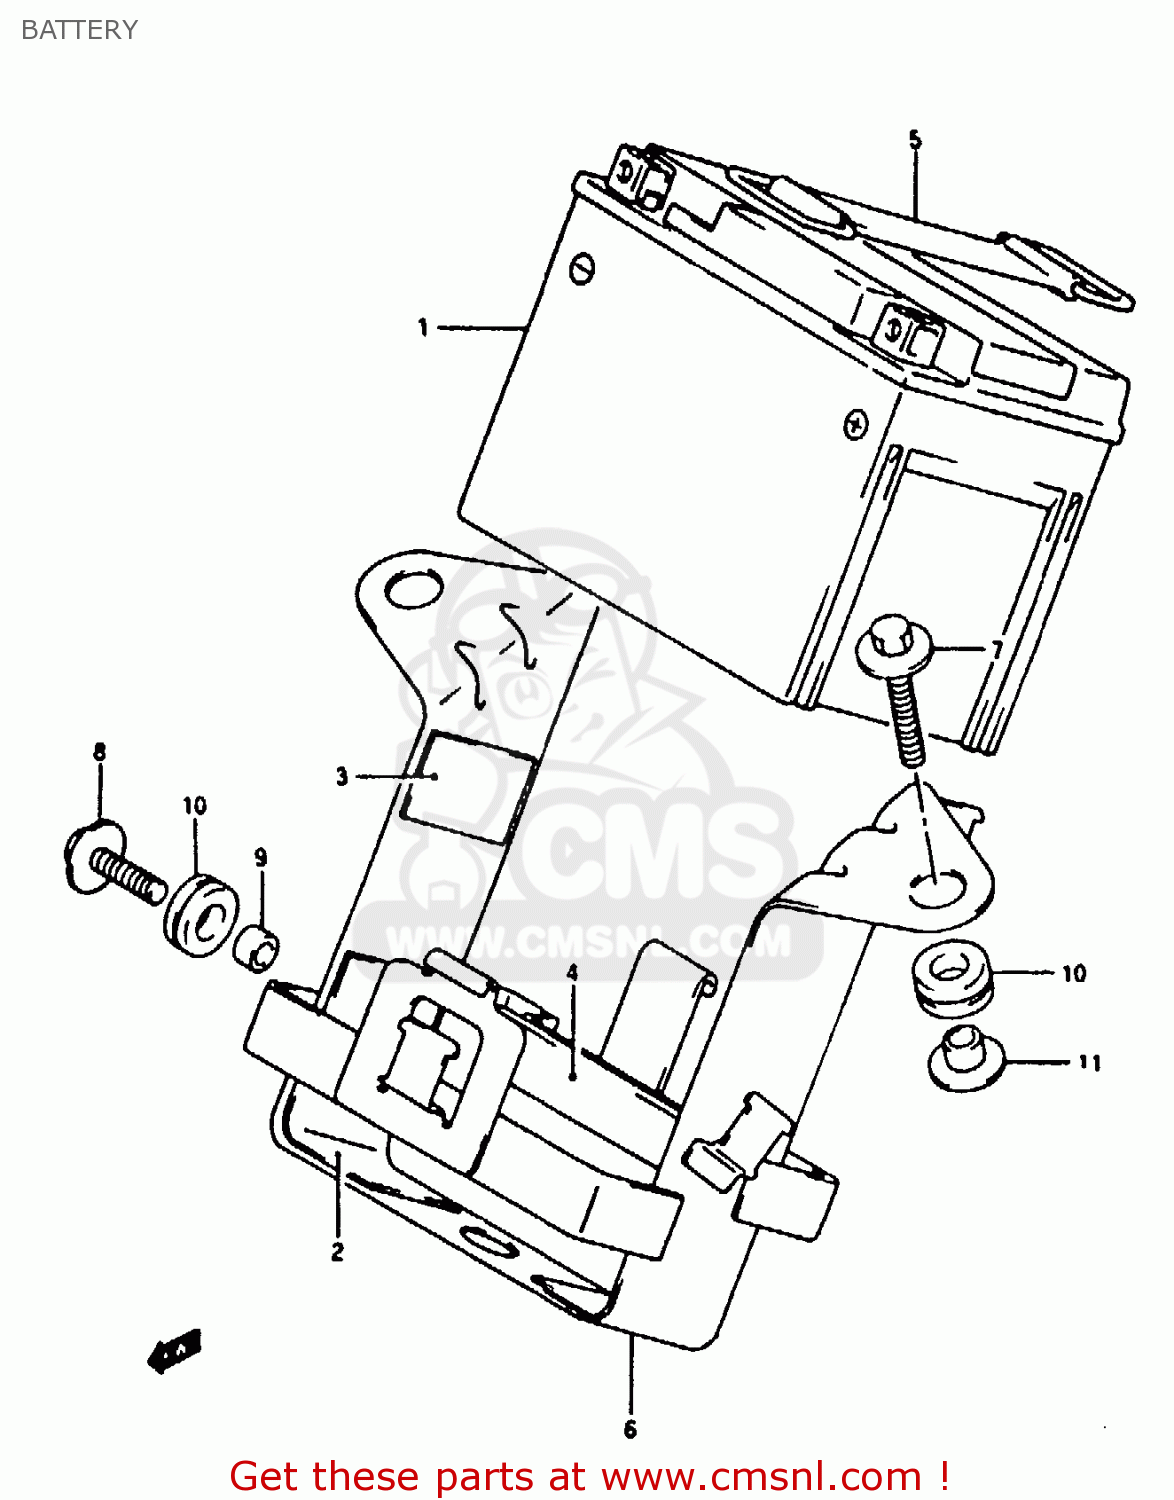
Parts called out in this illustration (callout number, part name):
1	BATTERY (YTX5L-BS, 12V4AH)
2	PROTECTOR(170X95X3.0)
3	PROTECTOR(170X95X3.0)
4	PROTECTOR,20X9
5	BAND
6	HOLDER, BATTERY
7	BOLT(6X25)
8	BOLT
9	SPACER(6.1X9X7.5)
10	CUSHION
11	PLATE,BATTERY HOLDER
